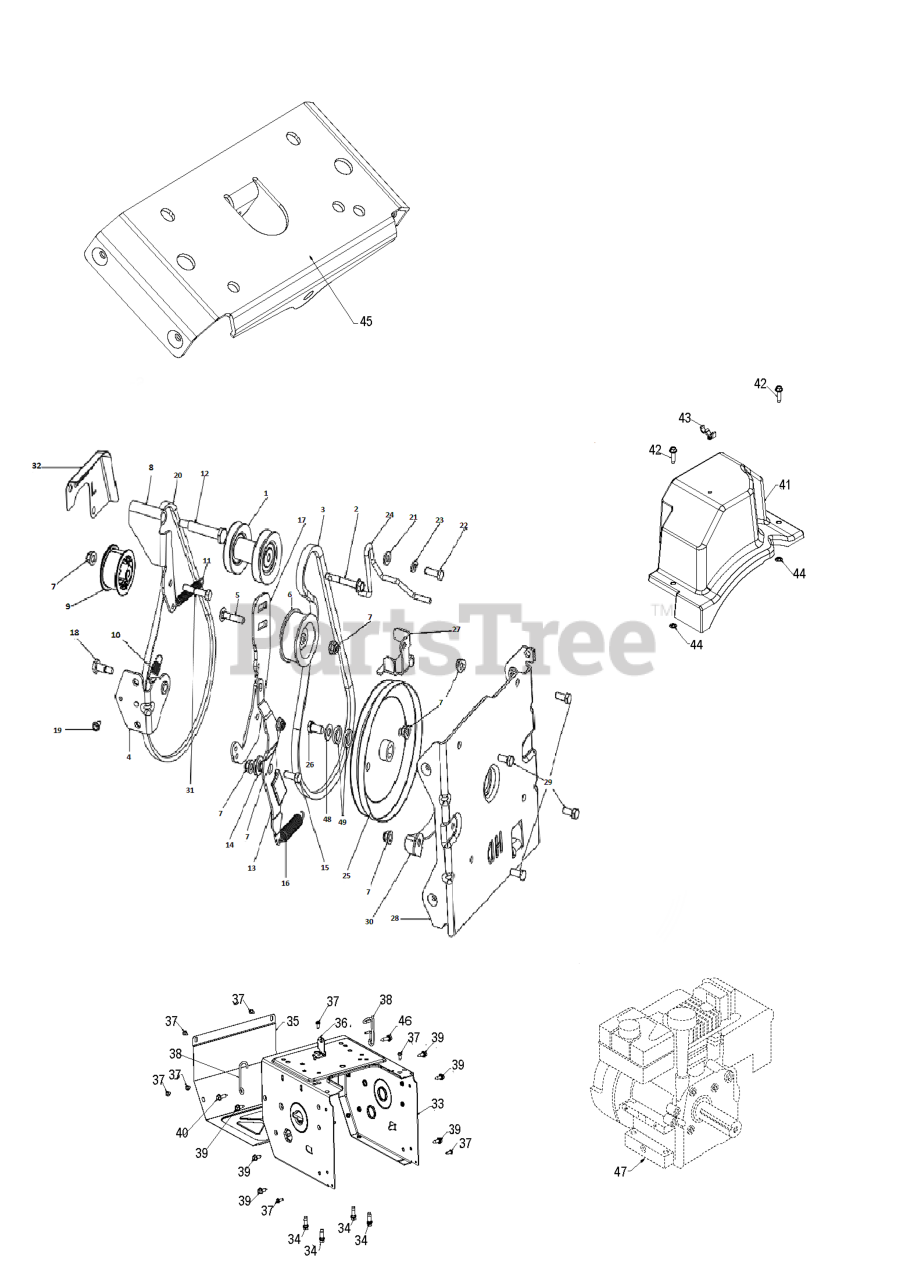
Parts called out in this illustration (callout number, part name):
1	PULLEY 4L GEAR - LC
2	BOLT.ENGINE.PULLEY
2	BOLTS
3	LOW CRANK IMPELLER BELT
4	BRACKET WELDMENT, IDLER ARM ZI
5	BOLT 5/16-18 CARRIAGE 1.5L
7	NUT HEXAGON FLANGE 5/16-18 ST
8	ARM DRIVE IDLER CLEAR ZINC PLA
9	PULLEYIDLER.2.0.W/SPACER.CZ
10	SPRING IDLER RETURN
11	SPRING RETURN IDLER ARM
12	BOLT 5/16-24X2.25 HEX HEAD SHO
13	ARM IMPELLER BRAKE
14	BUSHING.BRAKE.ARM
15	BOLT HEXAGON BOLT 5/16-18 X 7/
16	SPRING EXTENSION - BRAKE
17	ARM IDLER BLACK ZINC
18	SCREW HEX HEAD SHOULDER
21	WASHER 11/32 X 11/16 X 14 GA T
23	WASHER SPRING LOCK WASHER WITH
24	Belt Keepers
25	PULLEY IMPELLER DD 4L HD
26	SCREW HEXAGON HEAD FLANGE 3/8-
27	GUIDE.LOWER.AUGER.BELT.479
28	BRACKET AUGER HOUSING INTERFAC
29	SCREW HEXAGON HEAD SCREW 5/16-
30	BRACKET.BELT.KEEPER.LOWER.BLAC
31	BOLT, HEX 5/16-18X1-3/4
33	FRAME MS 668
34	BOLT 3/8-16X1-1/8
35	COVER COVER.FRAME MS668 ORANGE
36	BRACKET.SHIFTER.BZP
37	SCREW.HEX HEAD W/COLLAR 1/4-20
38	WIREFORM.SUPPORT.CABLE
39	BOLT.HEX.HD.WASHER.5/16-18X.75
40	SCREW HEX_SERR_HD_5_16-18X1.0
41	COVER BELT ASM. LOW CRANK
42	SCREW HEX WASH THDRL BLK 1_4-
44	PALNUT 1/4
45	BRACKET.FRAME.SUPPORT.BLACK
46	SCREW HEXAGON HEAD WITH COLLAR
47	ENGINE RATO 252CC (CARB)
47	ENGINE.LCT.254CC.ALT.SNO
47	ENGINE.LCT.254CC.STORMFOR.ALT
47	ENGINES
47	Engines
48	WASHER PLAIN WASHER 3/8 X 0.08
49	WASHER.SPACER.MANDREL
